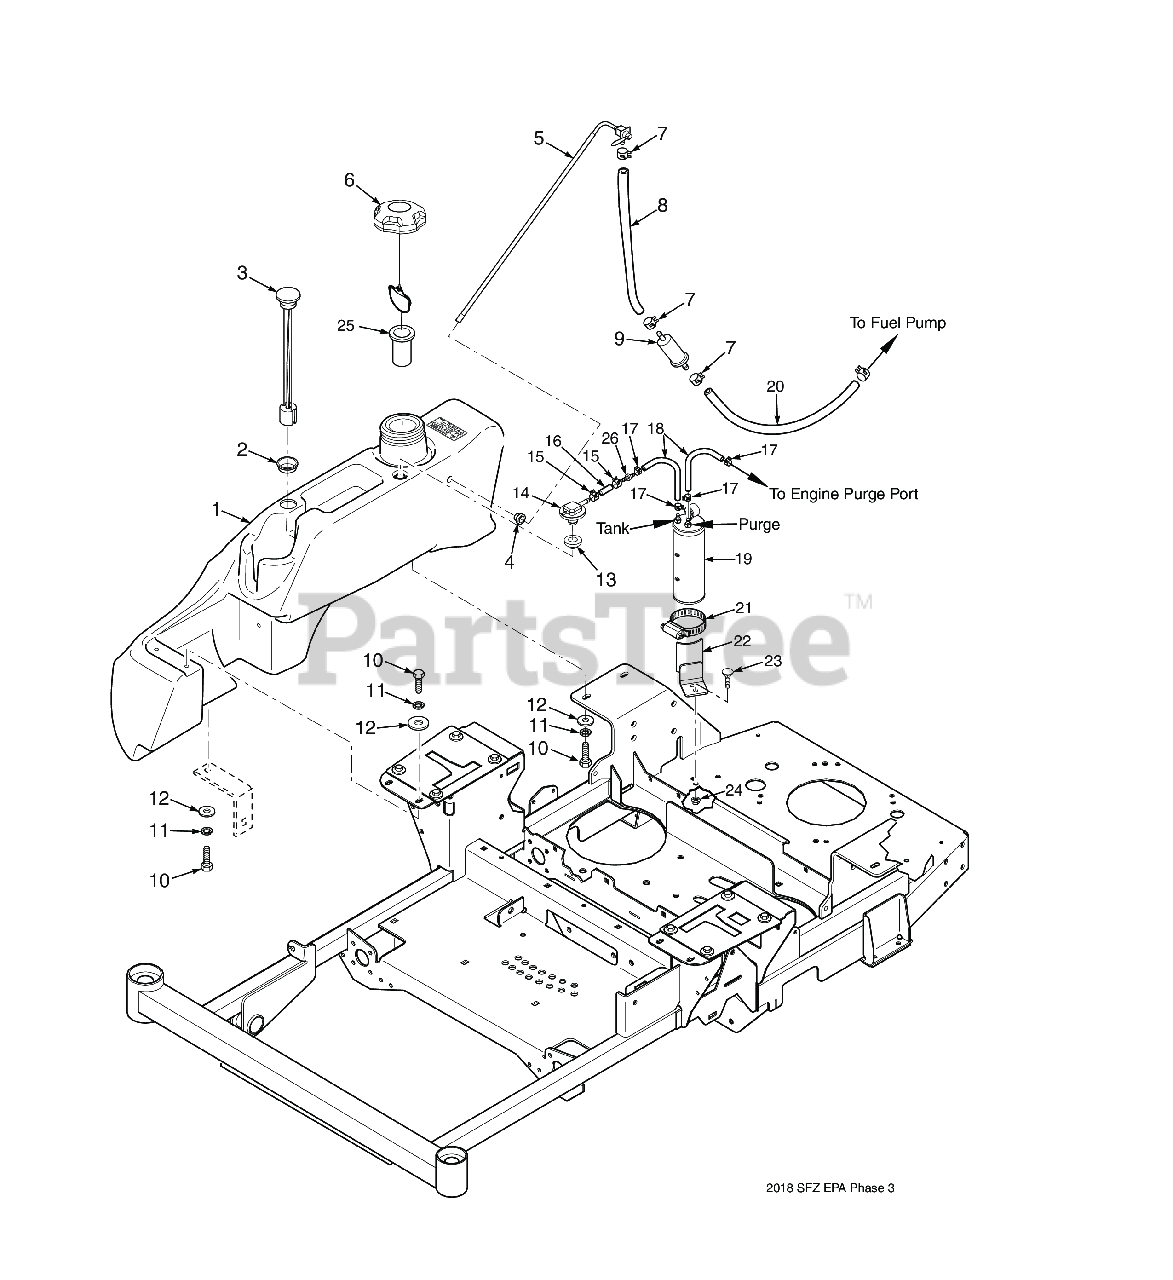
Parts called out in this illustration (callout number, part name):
1	Fuel Tank Assembly - SPZ (Includes 2,3,4,5,13,14)
2	Grommet, Fuel Gauge
3	Fuel Gauge Assembly
4	Bushing, 0.56" Dia. Viton
5	Fuel Tube Assembly
6	Fuel Cap w/ Tether (E.P.A.)
7	Clamp, Fuel Hose 1/4" Hose I.D.
8	Fuel Hose, 1/4" I.D. Non-Perm (791DFI Fuel Return) - Order by Inch
9	Fuel Filter
10	BOLT, SERRATED FLANGE HEX HEAD 5/16-18 X 3/4"
11	Lockwasher, 5/16 (.317 x .586 x .078) Helical Spring
12	Flatwasher, 5/16-.375 x .875 x .083 (35BV & 37BV-EFI)
13	Grommet, Viton,
14	Remote Vent, No Valve
15	CLAMP, FUEL HOSE(KAWASAKI ONLY)
16	Hose, 1/4" Vapor Recovery (order by inch)
17	Clamp, Vapor Recovery Hose 3/16"
18	Hose, Vapor Recovery 3/16" (order by inch)
19	Carbon Canister - SVR-52V / SVR-61V
20	Fuel Hose
21	Clamp, 3-1/2" Max. Dia.
22	Bracket Weldment, Kawasaki Models
23	Bolt, 5/16-18 x .75 RHSN Carriage
24	Nut, Serrated Flange 5/16-18 (Right Front Engine Mounting, Briggs and Kohler Only)
25	Tube, Fuel Tank Insert - 4"
26	Mender, 1/4 x 3/16 w/0.02 Hole
